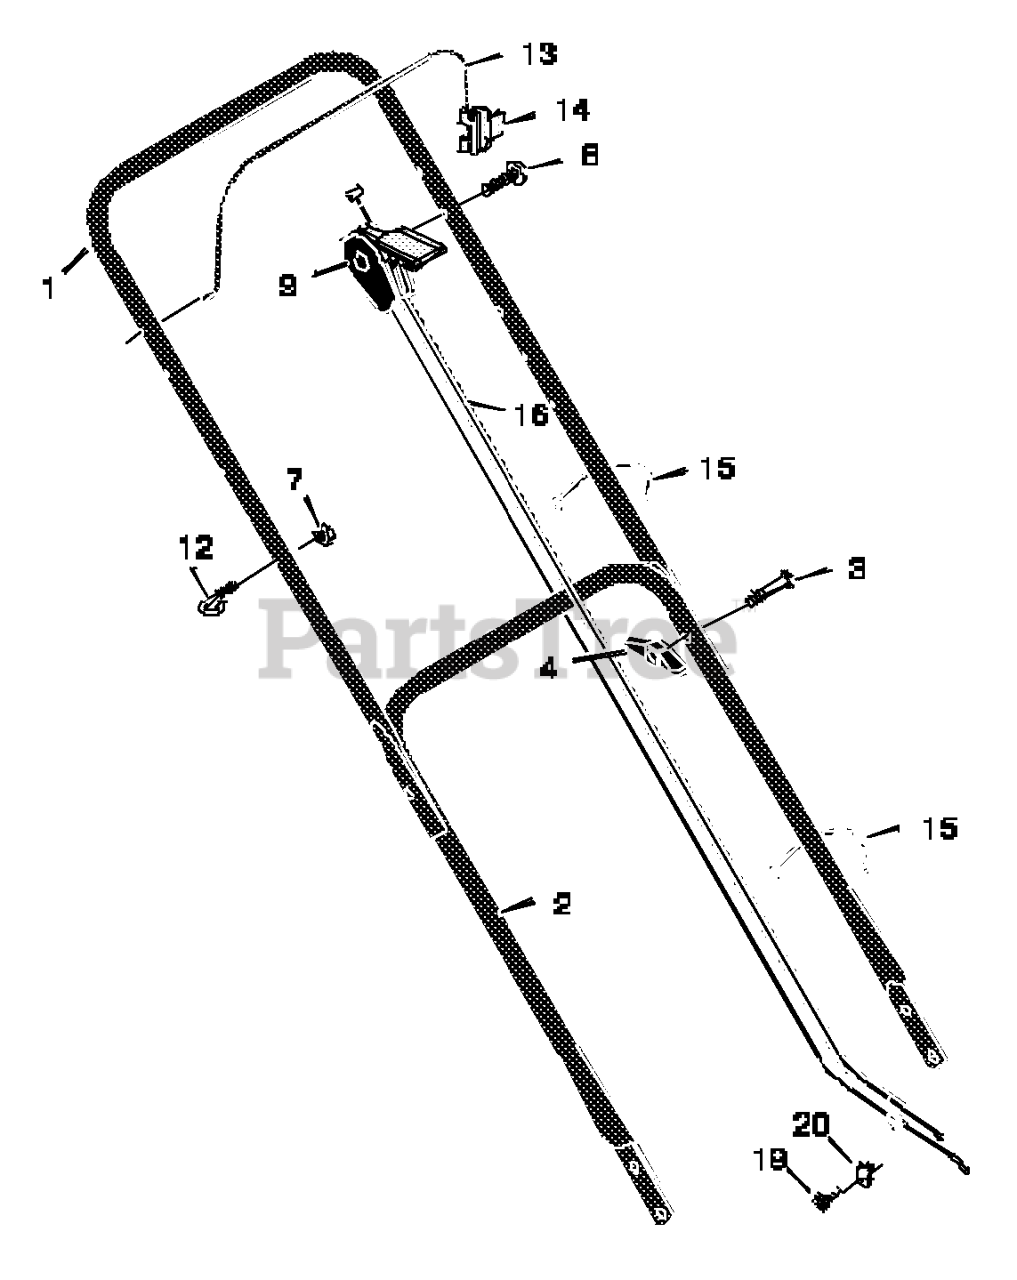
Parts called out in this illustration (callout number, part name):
1	Handle, Upper (Black)
2	Handle, Lower (Black)
4	Knob, Plastic
7	Locknut
9	Throttle Control
12	GUIDE, ROPE
13	Engine Stop Lever
14	Bracket, Stop Lever
15	Fastener, Cable
16	Engine Stop Cable
